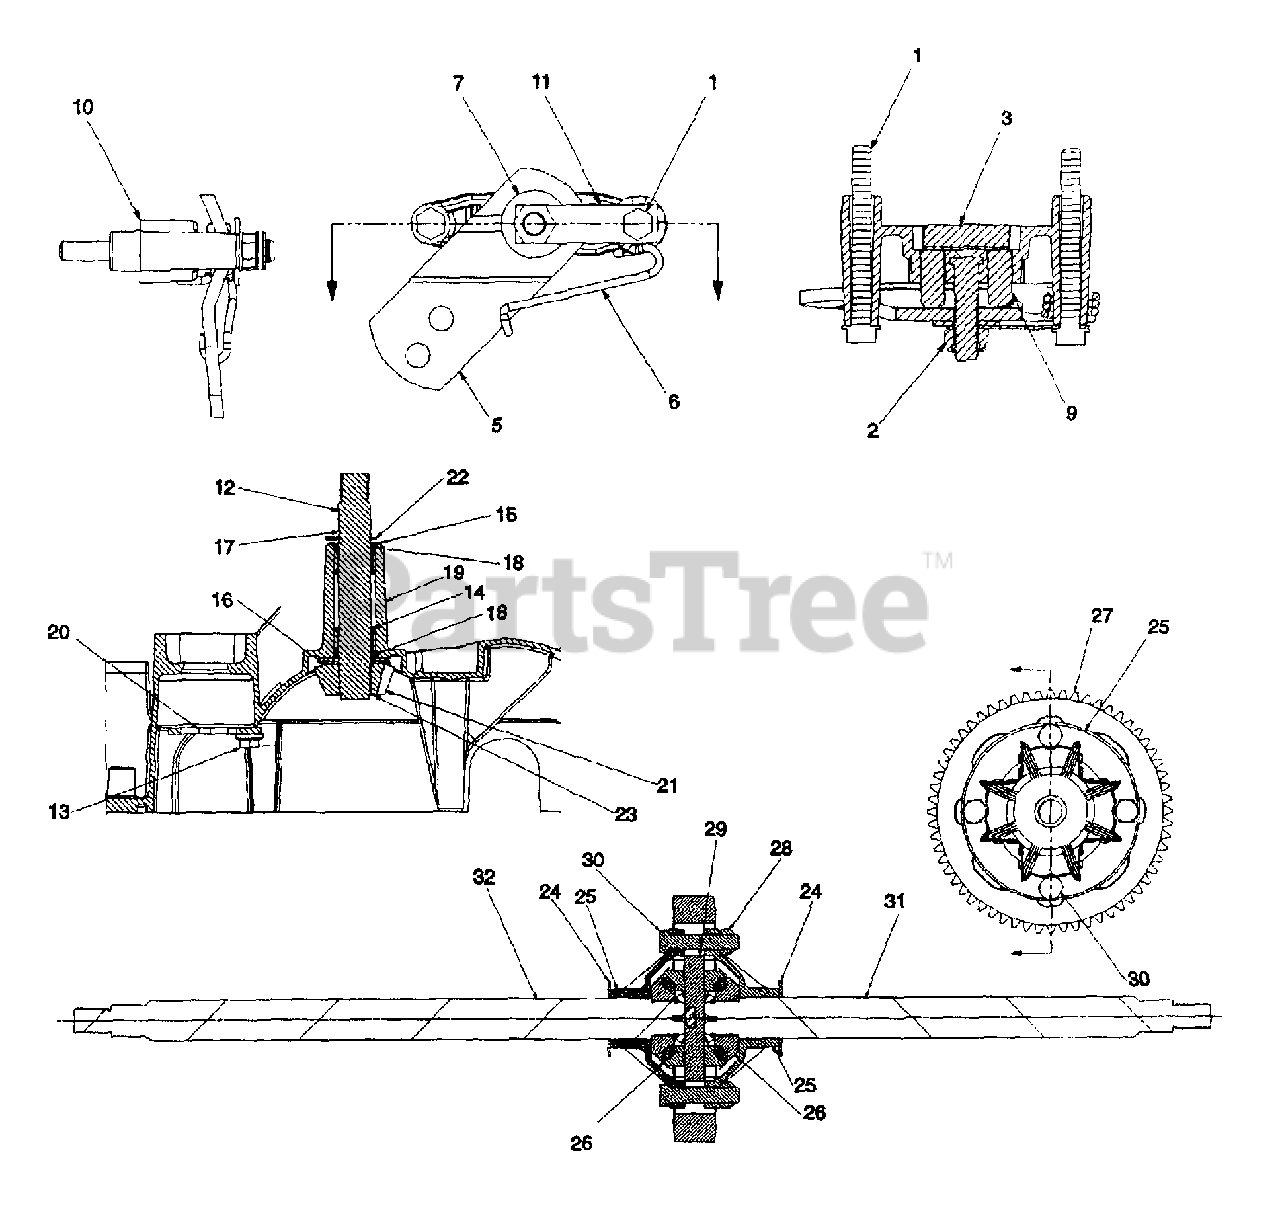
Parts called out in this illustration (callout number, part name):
1	Hex Wash. Hd. Scr. 1/4-20 x 2.37
2	Nylon L-Nut 5/16-24 Thd.
3	Brake Puck
5	Brake Arm
6	Torsion Spring
7	Fl-Wash. .343" I.D. x .88" O.D.
9	Brake Pin
10	Brake Yoke
11	Brake Anti Rotation Brkt.
12	Input Shaft
13	Hex Washer AB-Tap Scr. 1/4-14 x 1"
14	Needle Brg. .625" I.D.
15	Fl-Wash. 5/8" I.D. x 1" O.D.
16	Thrust Wash. .635" I.D. x 1.25" O.D.
17	Wire Ring
19	Upper Housing
20	Lockout Plate
21	Bevel Gear
22	Retainer Ring
23	Retainer Ring
24	Fl-Wash. 1" I.D. x 1.8" O.D.
25	Differential Housing
26	10T Miter Gear
27	Spur Gear 60T
28	Hex L-Nut 3/8-24 Thd.
29	Cross Shaft
30	Hex Bolt 3/8-24 x 2" Lg. (Gr. 5)
31	Axle Ass'y. - L.H.
32	Axle Ass'y. - R.H.
